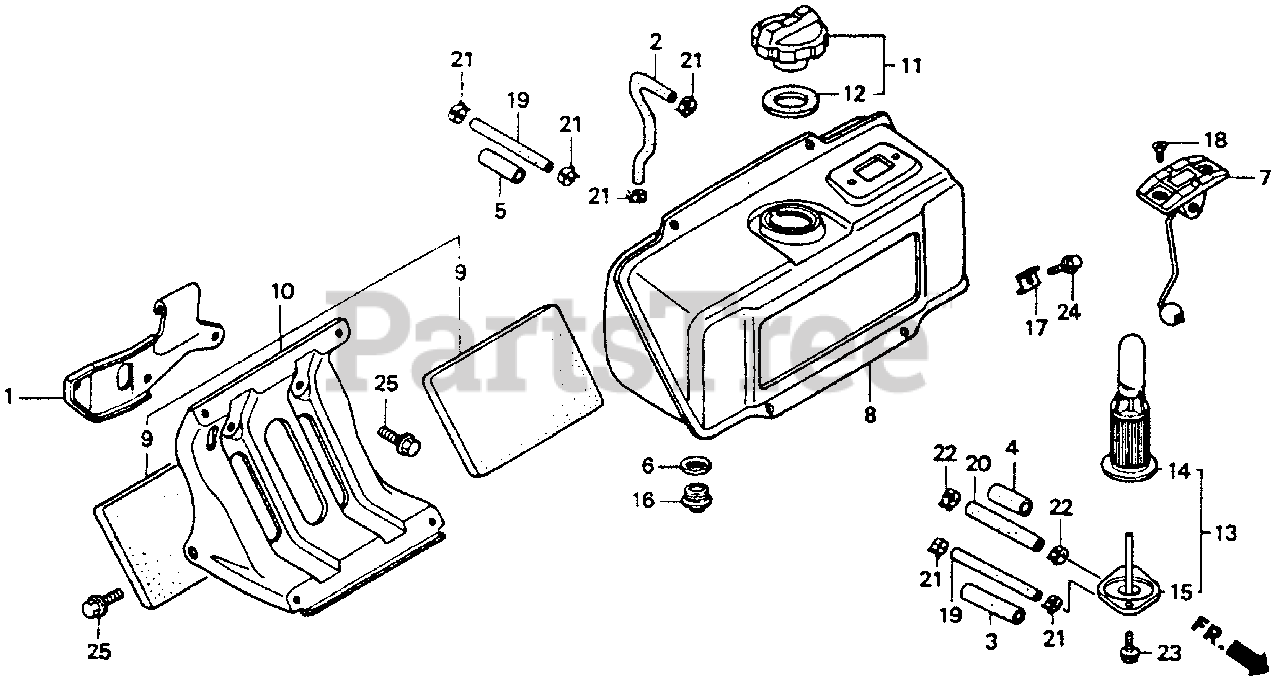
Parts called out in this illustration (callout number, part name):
1	HANGER, ENGINE
2	TUBE, FUEL
3	RUBBER, SUPPORTER (A)
4	RUBBER, SUPPORTER (B)
5	RUBBER, SUPPORTER (C)
6	GASKET
7	GAUGE ASSY., FUEL
8	TANK, FUEL *R8* (GAUGE) (BRIGHT RED)
9	SEAT, TANK STAY
10	STAY, FUEL TANK
11	CAP, FUEL FILLER
12	GASKET, FUEL FILLER CAP
13	FILTER ASSY., FUEL
14	STRAINER
15	BODY, STRAINER
16	BOLT, DRAIN
17	WASHER, SPECIAL (6MM)
18	SCREW, FLAT (5X10)
19	BULK HOSE, FUEL (4.5X3000) (4.5X100)
20	BULK HOSE, FUEL (8X1000) (8X90)
21	CLIP, TUBE (D8)
22	CLIP, TUBE (D12.5)
23	BOLT, FLANGE (6X12)
24	BOLT, FLANGE (6X14)
25	BOLT, FLANGE (8X22)
